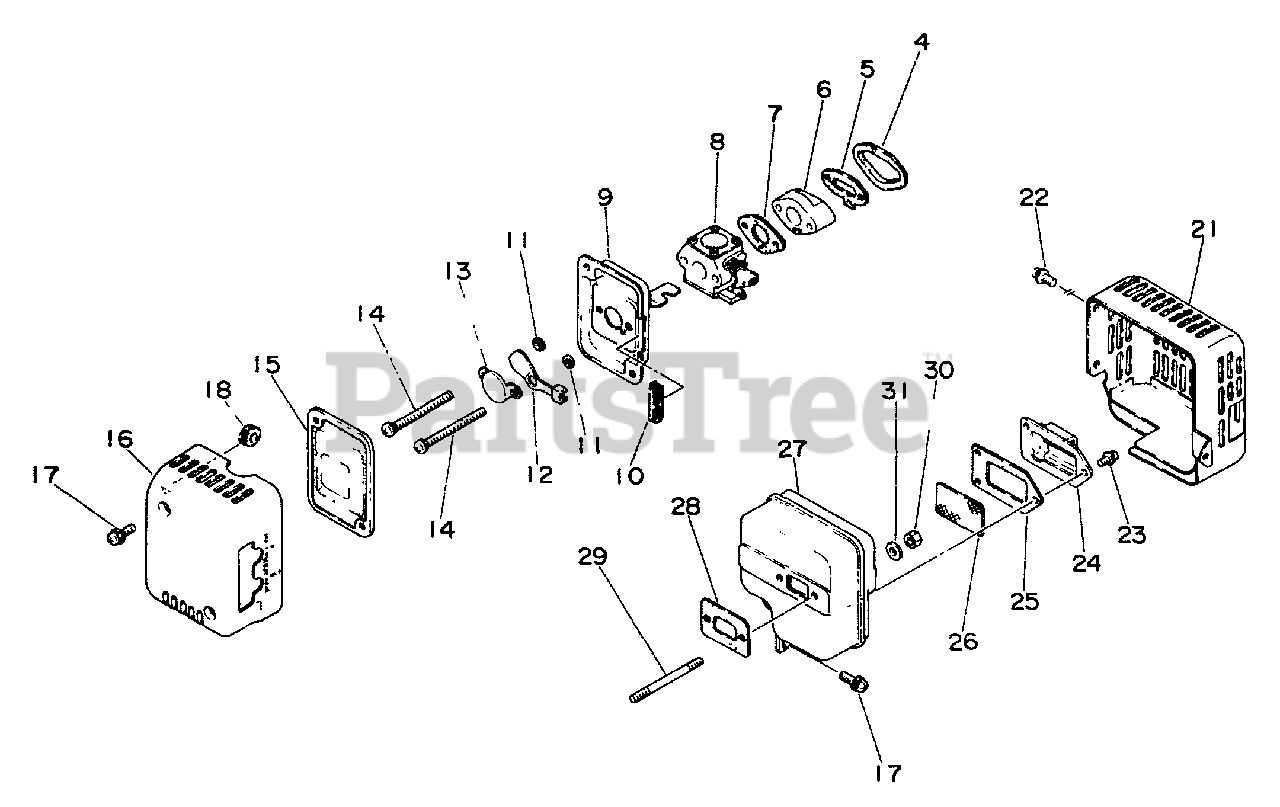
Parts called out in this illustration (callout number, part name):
5	GASKET, INTAKE
6	INSULATOR, INTAKE
7	GASKET, INTAKE
8	CARBURETOR - WA-141
9	CASE, AIR FILTER
11	WASHER 5.2×8×0.8T
12	SHUTTER, CHOKE
14	SCREW 5×60
15	FILTER, AIR
16	COVER, AIR FILTER
17	SCREW 5×14
21	COVER, MUFFLER
22	SCREW 5×10
23	SCREW 4×8
24	LID, MUFFLER
25	GASKET, EXHAUST
26	SCREEN, SPARK ARRESTER
27	CASE, MUFFLER
28	GASKET, EXHAUST
29	BOLT, STUD
30	LOCKNUT - 5
31	WASHER 5.5×12×0.8
